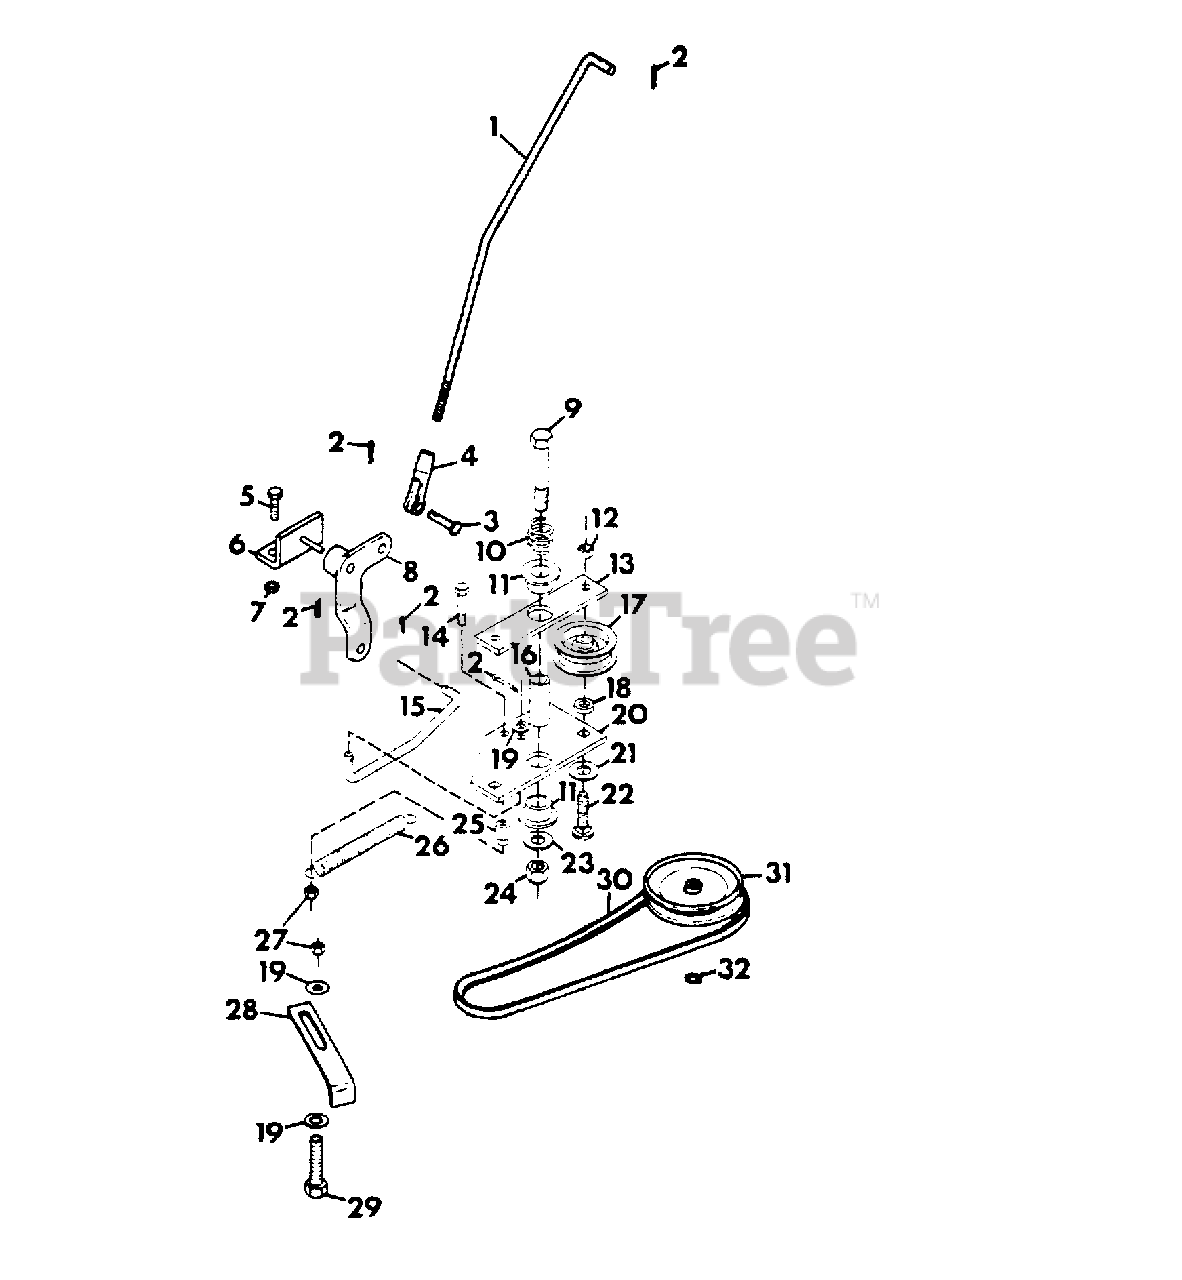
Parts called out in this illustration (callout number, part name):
1	ROD, NEUTRAL CLUTCH
2	PIN, COTTER .09X.75
3	PIN, CLEVIS .375X.948
4	CLEVIS, 3/8-24 ADJUSTABLE
5	BOLT, HEX 3/8-16X1.00
6	WELDMENT, CLUTCH LEVER BRACKET
7	NUT, LOCK 3/8-16
8	LEVER, CLUTCH PIVOT
9	BOLT, HEX 1/2-13X3.00
10	SPRING, COMP. 1X.80X36 LB/N
11	BUSHING, NYLON
12	NUT, LOCK 3/8-16
13	PLATE, IDLER
14	BOLT, HEX 5/16-18X1.50
15	ROD, IDLER
16	SPACER
17	SHEAVE, IDLER
18	SPACER, IDLER
19	WASHER, FLAT .344X.688X.065
20	PLATE, IDLER
21	WASHER, FLAT .531X1.063X.095
22	BOLT 3/8-16X1.75 RD HD SQ NK
23	WASHER, FLAT .531X1.250X.100
24	NUT, LOCK 1/2-13
25	SPACER, SHIPPER SHAFT GUIDE
26	SPRING, NEUTRAL CLUTCH
27	NUT, LOCK 5/16-18
28	GUIDE, V-BELT
29	BOLT, HEX 5/16-18X1.75
30	BELT, V-DRIVE
31	SHEAVE, TRANSMISSION
32	RING, RETAINING
